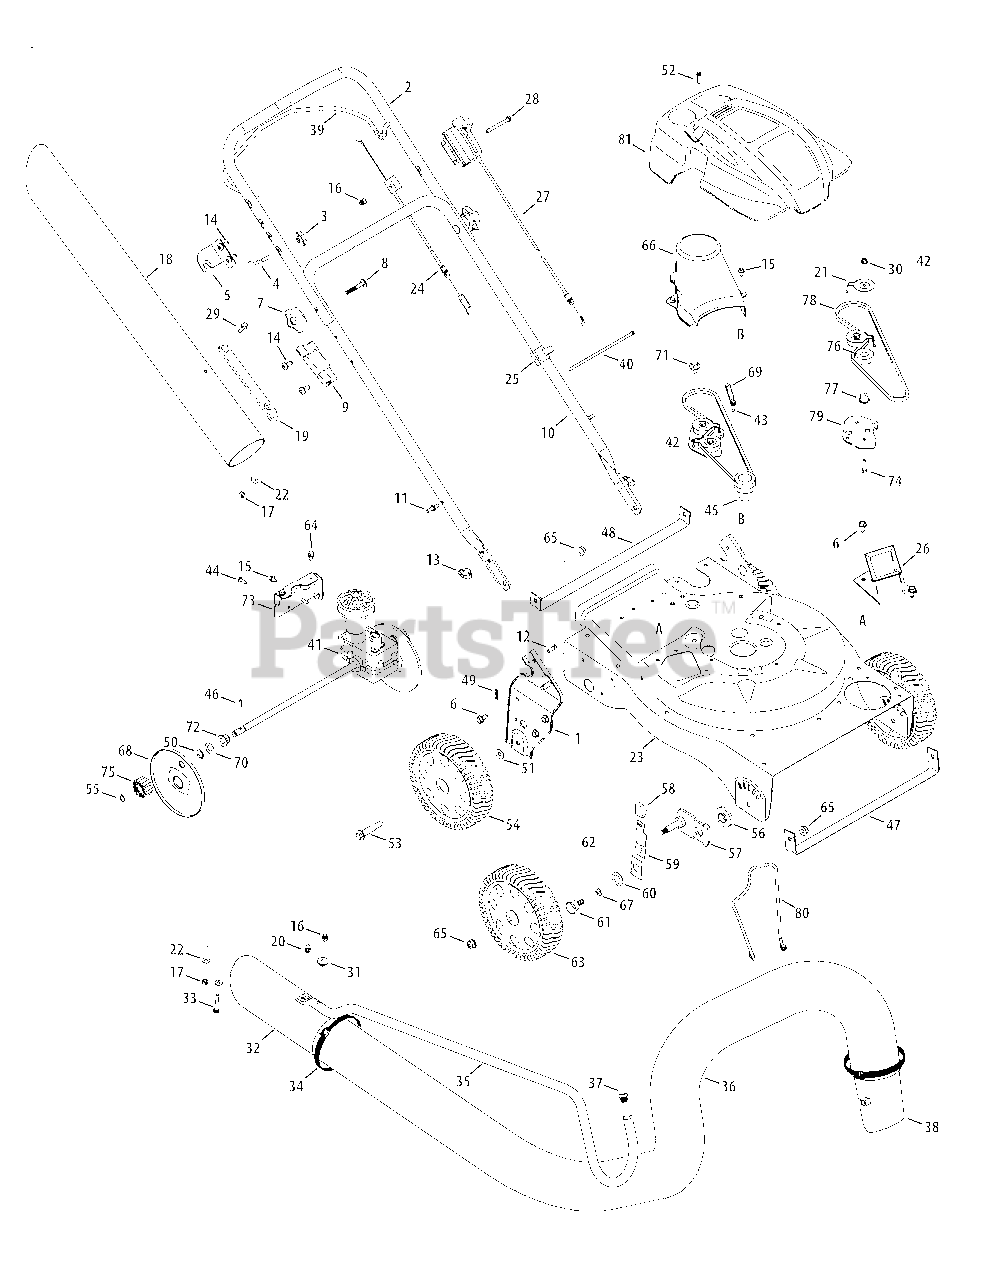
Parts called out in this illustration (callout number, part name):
1	Handle Bracket Ass’y RH
2	Upper Handle
5	Upper Handle Bracket
6	Hex Cap Screw, 5/16-12 x.750
7	Handle Knob, 5/16-18
8	Carriage Bolt
9	Nozzle Handle Clip
12	Carriage Screw, 1/4-20 x.75
13	Wing Nut, 1/4-20
14	TT Screw, 5/16-18 x .750
15	Screw, 1/4-20 x .500
16	Cap Lock Nut, 1/4-20
17	Hex Lock Nut, 1/4-20
18	Hose Extension
19	Chute Strap
21	Belt Keeper
22	Flat Washer.271 ID x.630 OD
23	Upper Flail Housing
24	Drive Control Cable
25	Cable Guide
26	Chipper Chute Assembly
27	Speed Control Cable
28	Hex Screw, 1/4-20 x 2.50
29	Screw, 1/4-20 x .75
30	Flange Lock Nut, 1/4-20
32	Hose Nozzle
33	Hex Cap Screw, 1/4-20 x 2.625
34	Adjustment Clamp
36	Vacuum Hose
37	Handle Plug
38	Hose Adapter
39	Drive Control
40	Cable Tie
41	Transmission Assembly
42	Idler Assembly
43	Shoulder Screw, #12-24 x .30 x .46
44	Screw, #12-16 x .750
45	Impeller Hub
46	Dowel Pin
47	Front Wheel Support Brace
48	Rear Wheel Support Brace
49	Cotter Pin
51	Flat Washer, .406 x .875 x .105
52	Screw, #12-16 x 1.00
53	Shoulder Screw, 3/8-16
54	Wheel, 8 x 2.125
55	Snap Ring
56	Height Adjustment Bearing
57	Pivot Arm Assembly
58	Height Adjustment Knob
59	Spring Lever
60	Bell Washer, .760 ID x.25 OD
61	Shoulder Screw, .750 x.500
62	Height Lever Assembly
63	Wheel 8 x 2
64	Screw, 1/4-20 x .625
65	Flange Lock Nut, 3/8-16
66	Belt Cover
67	Thrust Washer, .375 ID x.70 OD
68	Wheel Cover
69	Extension Spring, .375 x 2.95
70	Flat Wash, .508ID x1.00OD x.020
71	Shoulder Screw, .560 x.165
72	Drive Axle Bushing
73	Transmission Mounting Bracket
74	Screw, 1/4-20 x 1.00
75	Spur Gear - RH
75	Spur Gear - LH
76	Ball Bearing
77	Flange Spacer,.260 x.659 x.517
78	Belt, 3/8 x 32.5
79	Idler Bracket
80	Tube Holder
81	Engine Shroud
